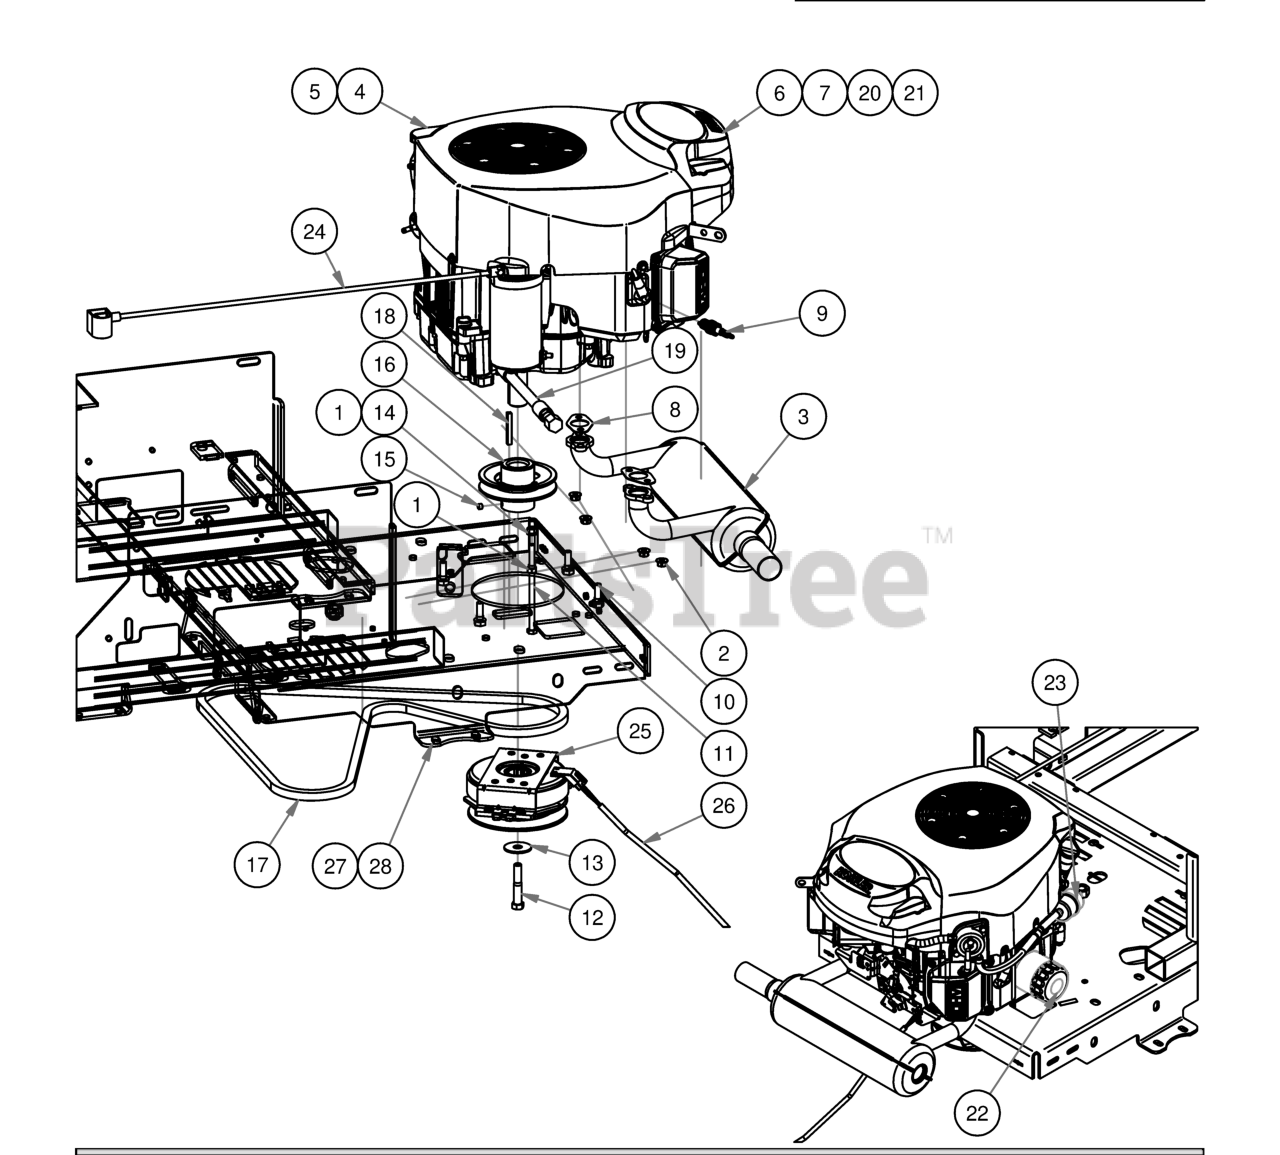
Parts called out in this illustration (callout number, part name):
2	M8 Flange Nut for Kohler Exhaust
3	Kohler Muffler
4	Kohler KT740 Engine
5	Kohler KT745 Engine
6	Kohler KT745 Air Pre-Cleaner
7	Kohler KT745 Air Filter Element
8	Exhaust Gasket
9	Spark Plug
10	3/8 x 1 1/8 bolt
11	5/16-18 x 5-1/2 GR 5 Hex Bolt
12	7/16"-20 x 2.5" Hex Bolt Gr. 8
13	1/2" Belleville Washer
14	5/16" Lock Washer
15	5/16 Set Screw
16	4 3/4 Motor Pulley
18	1/4 x 2 Square key Stock
19	Oil drain Hose
20	Kohler KT740 Precleaner
21	Kohler KT740 Air Element
22	725 & 747 Kohler Oil Filter
23	Universal Inline Fuel Filter
24	24" Black Ground Cable
26	Clutch Pigtail
27	2017 MZ/ZT 54"-60" Frame
28	2017 MZ/ZT 42"-48" Frame
